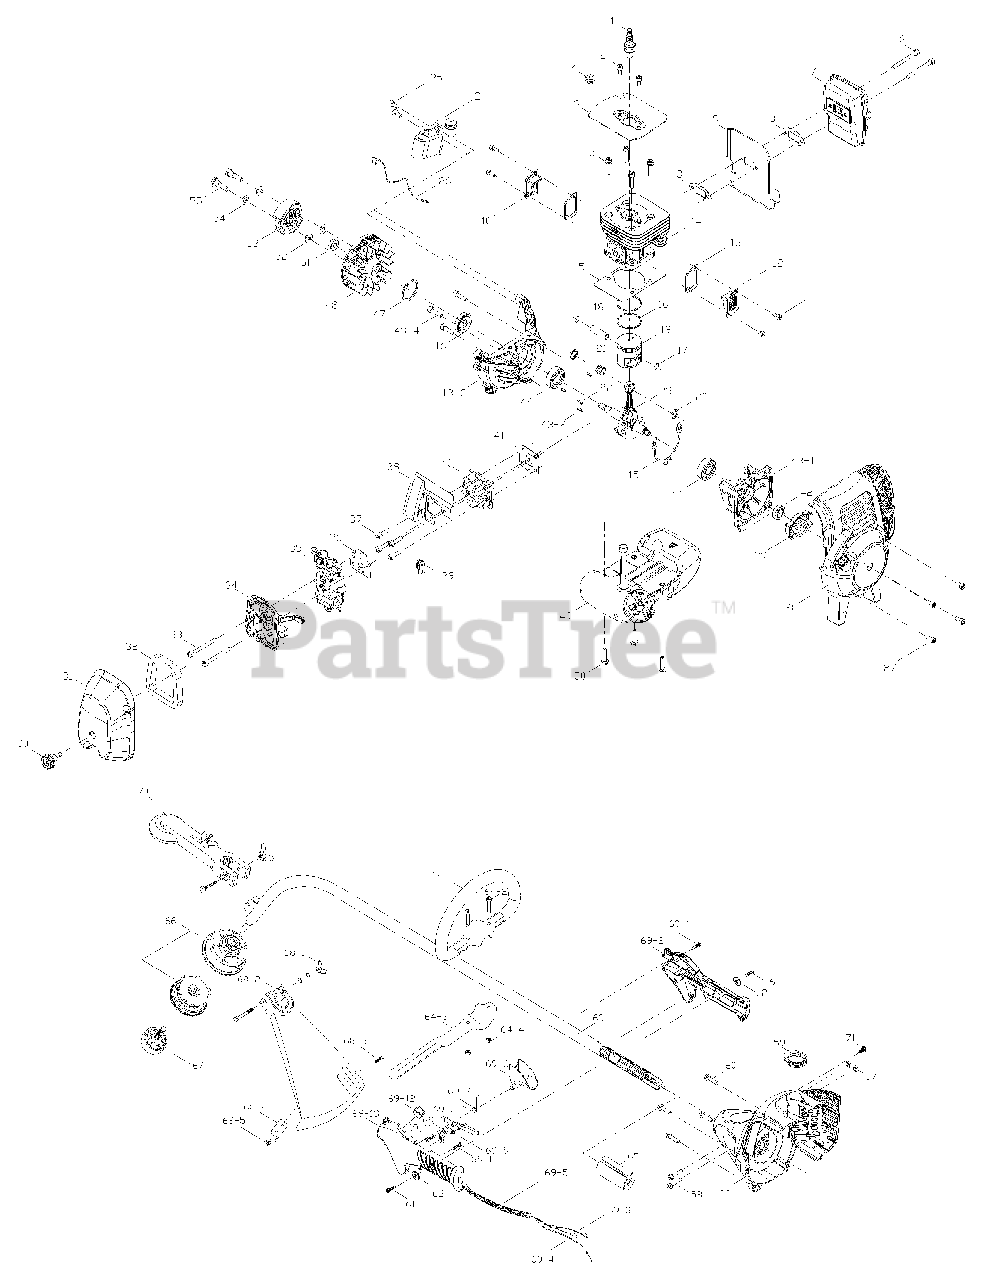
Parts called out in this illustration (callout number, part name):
1	SPARK PLUG
3	PLATE (SPARK SIDE)
7	MUFFLE ASS'Y
8	MUFFLE GASKET
9	MUFFLE PLATE
10	COVER (FLYWHEEL SIDE)
14	CYLINDER
16	PISTON RING
18	PISTON PIN
20	AXLS COVER
21	NEEDLE BEARING
23	CRANK/ROD ASS'Y
24	IGNITION COIL
26	COIL WIRE
28	STARTER HOUSING ASS'Y
29	PAWLS ASS'Y
30	KNOB
31	FILTER COVER
34	FILTER ASS'Y
35	CARBURETOR
36	CARBURETOR GASKET
40	INSULATOR
41	INSULATOR GASKET
43	CRANKCASE ASS'Y
43-1	CRANKCASE (STARTER SIDE)
43-3	CRANKCASE (FLYWHEEL SIDE)
47	C RING
49	FUEL TANK ASS'Y
51	NUT
53	CLUTCH (WITH SPRING)
54	WAVE PLATE
56	TRANSMISSION SUPPORT ASS'Y
63	BAG BEHIND
64	HANDLE ASS'Y
64-1	HOUSING, HANDLE-UPPER
64-3	HOUSING, HANDLE-UNDER
66	SRTINGHEAD ASS'Y
67	KNOB ASS'Y
68	COVER ASS'Y
68-1	PARTS BAG
68-4	KIT, KNIFE
69	HANDLE ASS'Y
69-2	HOUSING, HANDLE
69-3	WIRE ASS'Y, SWITCH
69-4	THROTTLE CABLE
69-8	LIBERATE SHAFT
69-10	LIBERATE CHUNK
69-13	HOUSING, HANDLE
70	TRIMMER WHEEL
